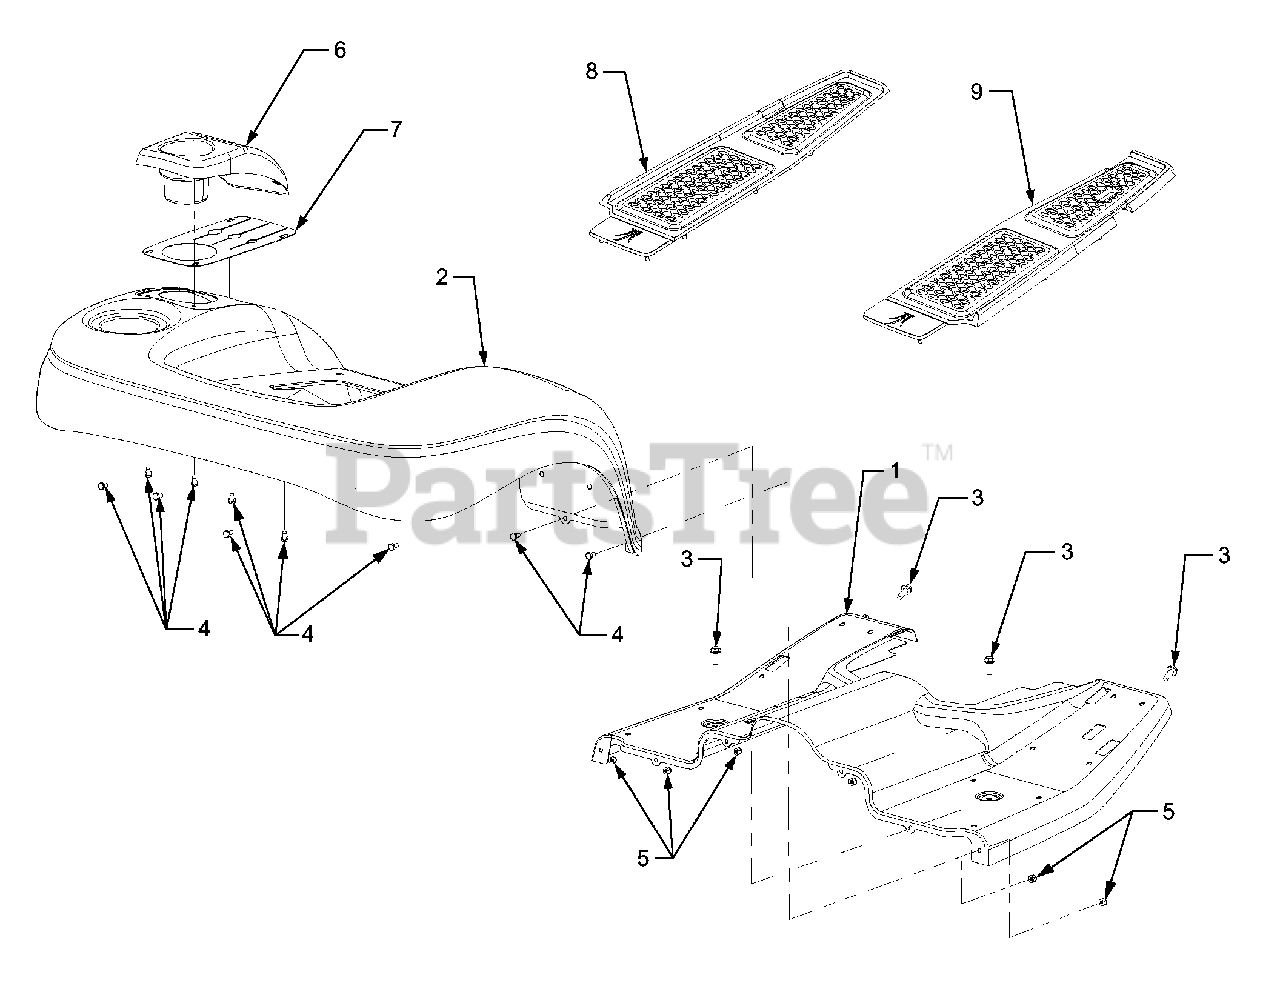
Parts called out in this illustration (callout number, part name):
1	Running Board
2	Fender
3	Screw, Hex Wash. Hd. Tapp 5/16-18 x 1.0
4	Screw, Hex Cap, 1/4-20 x .5 GR5
5	Nut, Hex Lock, 1/4-20
6	Cover, Lift Lever
7	Flap, Lift Lever
8	Pad. Floor LH
9	Pad. Floor RH
